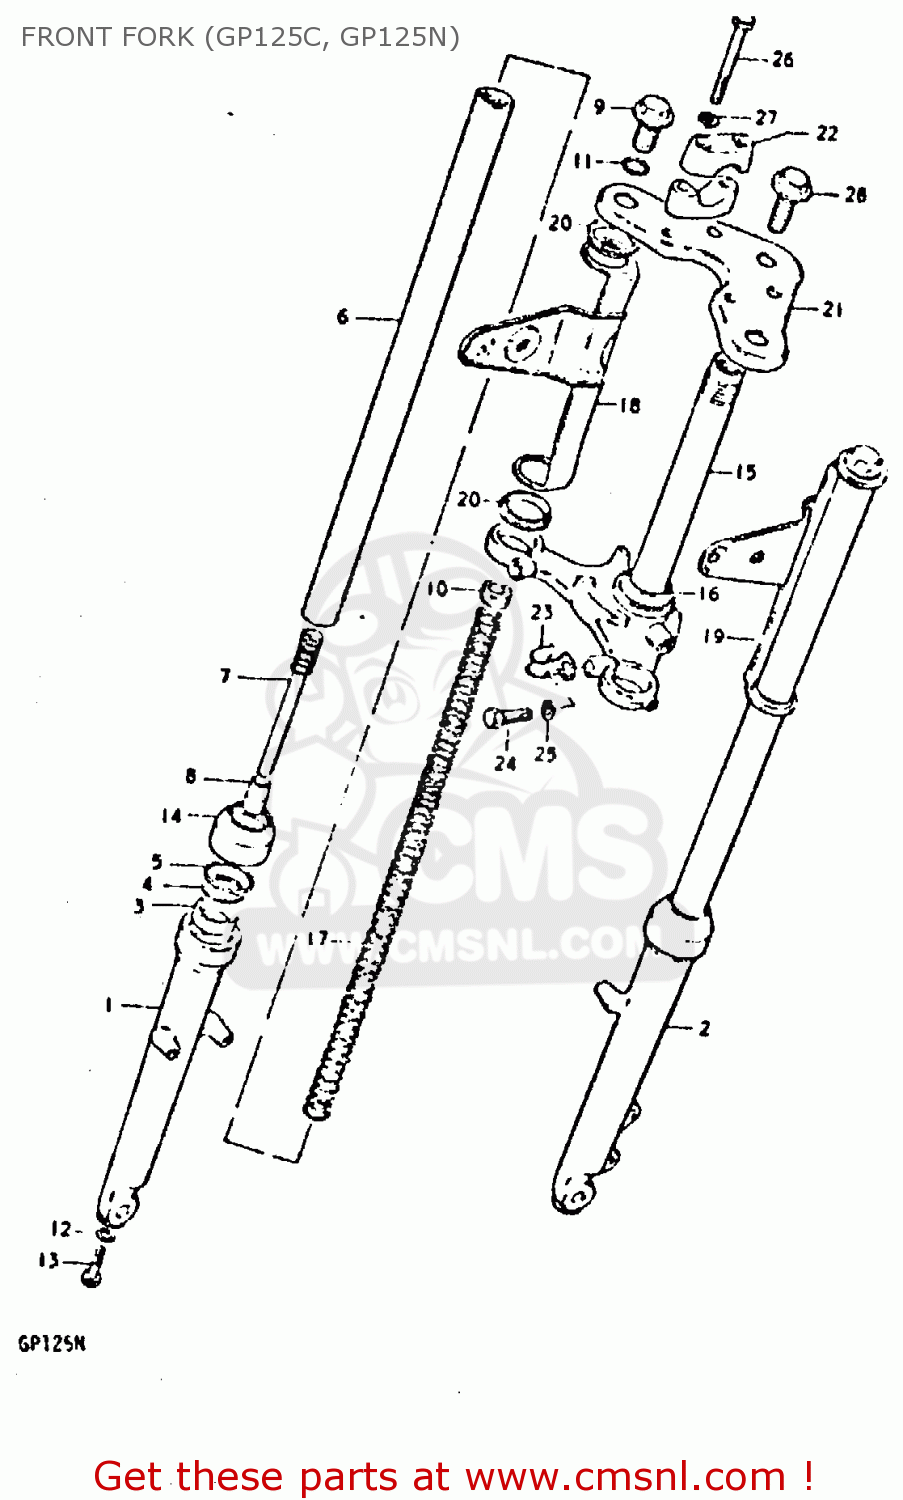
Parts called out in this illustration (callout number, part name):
1	OUTER TUBE, RH
2	OUTER TUBE, LH
3	OIL SEAL,FRONT FORK
4	WASHER,FRONT FORK
5	RING,SNAP
6	INNER TUBE
7	CYLINDER
8	PIECE,OIL LOCK
9	CAP
10	NUT
11	O RING
12	GASKET (NAS)
13	BOLT
14	SEAL,DUST
15	STEM
16	RACE,STEERING OUTER LWR
17	SPRING
18	COVER, RH
19	COVER, LH
20	GASKET
21	STEM HEAD
22	HOLDER,HANDLE UPR
23	CLIP
24	BOLT,FR FORK LWR(12X33)
25	WASHER,LOCK 12
26	BOLT
27	LOCK WASHER
28	BOLT
